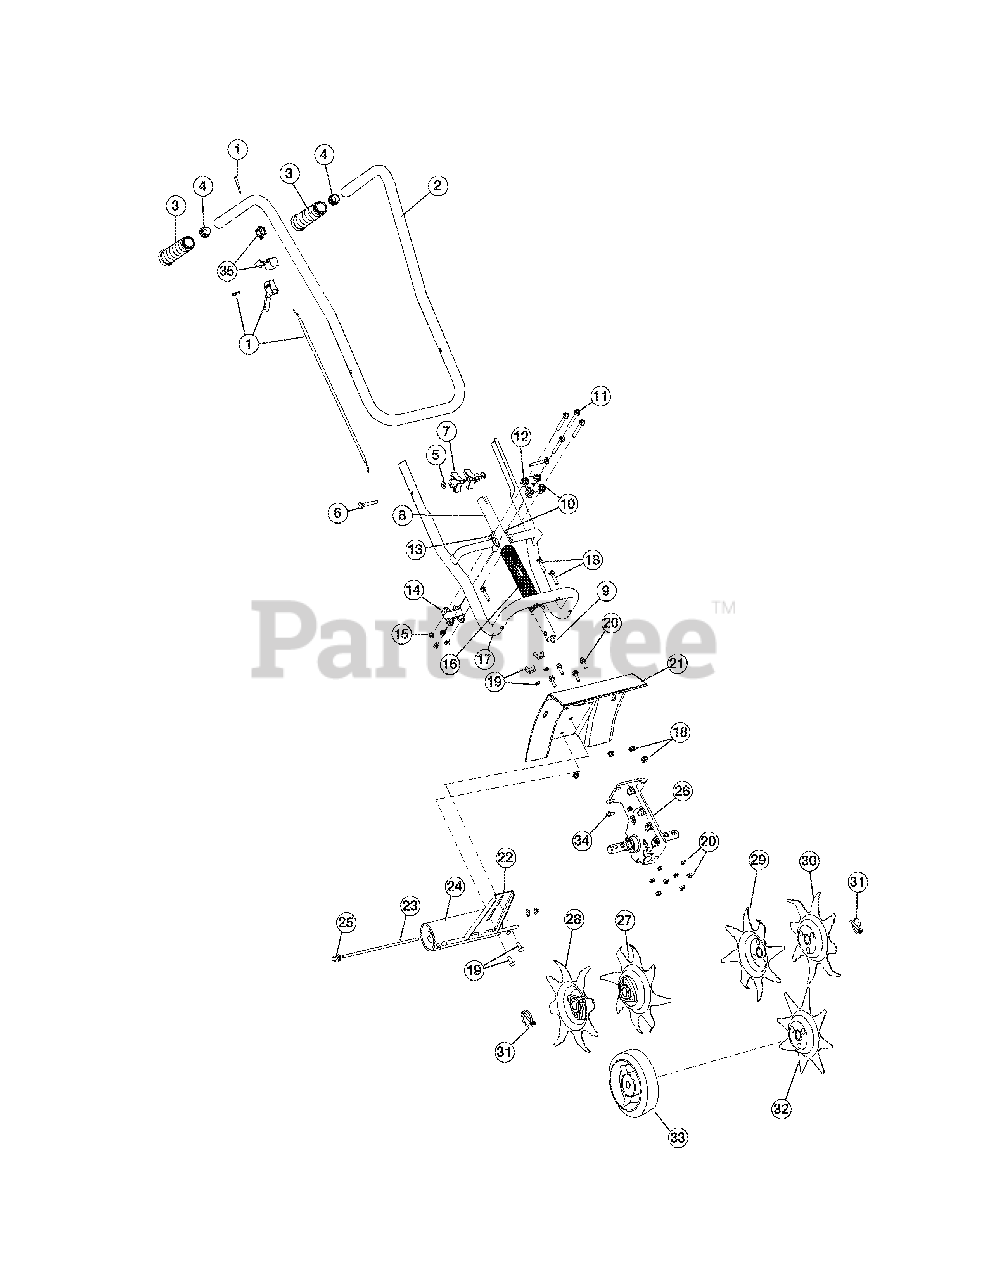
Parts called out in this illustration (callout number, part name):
1	Throttle Trigger and Cable Assembly
2	Handle Bar Assembliy, Upper (includes 3 & 4)
4	Tube Closure
5	Washer
7	Knob, 3 prong
8	Drive Shaft Housing Assembly
9	Flexible Drive Shaft
10	Handle Bracket Assembly (includes 11-15)
12	Upper Handle Clamp
13	Middle Handle Clamp
14	Lower Handle Clamp
17	Lower Handle Bar
18	Hardware, Handle Bar Mounting (lower)
19	Wheel Bracket Mounting Hardware
20	Guard Mounting Hardware
22	Roller Bracket Assembly
23	Roller Axle
24	Roller
25	Roller Cap
26	Gearbox Assembly
27	Inner Tine (right side)
28	Outer Tine (right side)
29	Inner Tine (left side)
30	Outer Tine (left side)
31	Click Pin
32	Edger Tine
33	Edger Wheel
34	Sleeve Retainer Bolt
